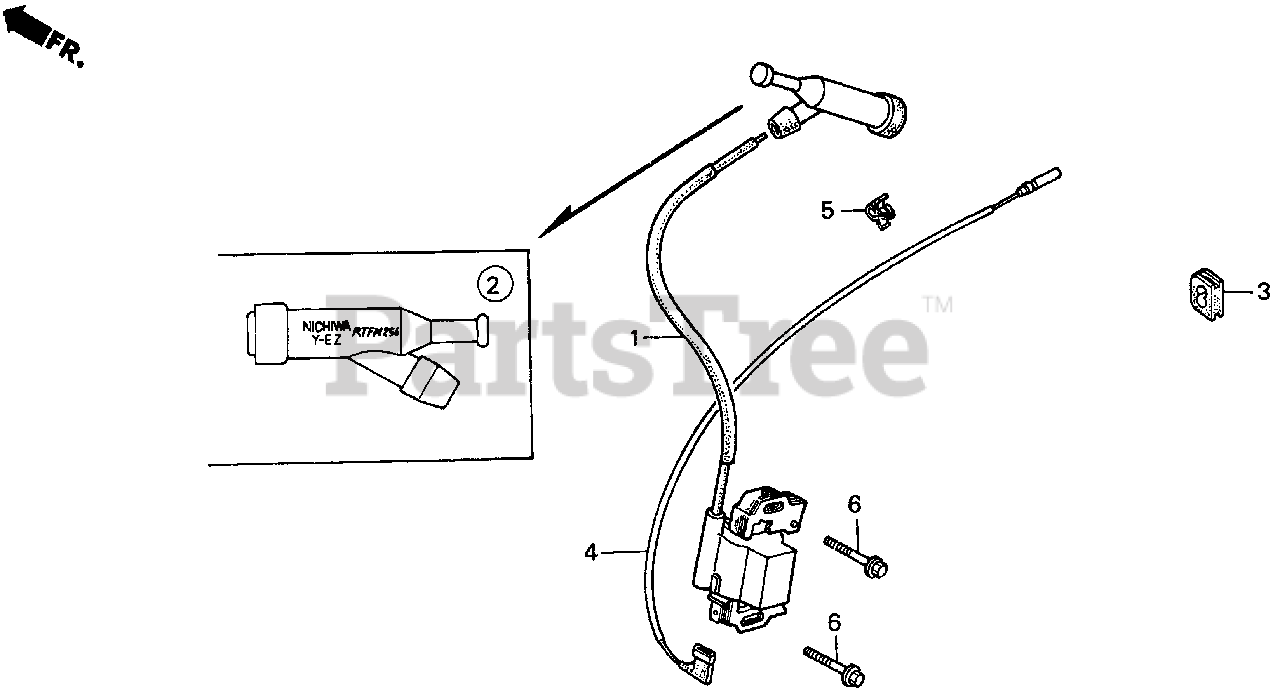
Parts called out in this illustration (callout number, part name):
1	COIL ASSY., IGNITION
2	CAP ASSY., NOISE SUPPRESSOR
3	GROMMET, WIRE
4	WIRE, STOP SWITCH (NOT AVAILABLE)
5	HOLDER, STOP SWITCH WIRE
6	BOLT, FLANGE (6X28)
